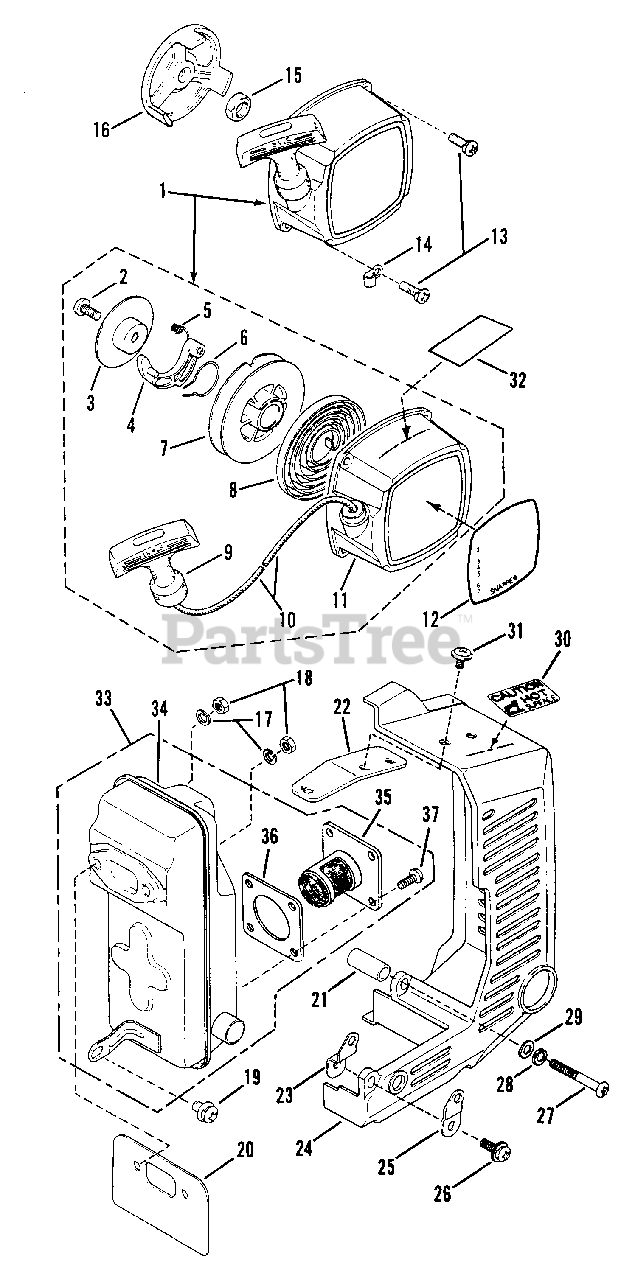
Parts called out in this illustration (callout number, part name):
1	RECOIL STARTER ASSM'Y.
3	PLATE, Friction
4	RATCHET
5	SPRING, Return
6	SPRING, Friction
7	REEL
8	SPRING, Spiral
9	KNOB, Starter
10	ROPE, Starter
11	CASE, Starter
12	DECAL, Instruction
16	PULLEY, Starter
17	LOCKWASHER
20	GASKET, Muffler
22	BRACKET
23	BRACKET
24	COVER, Muffler
25	BRACKET
28	LOCKWASHER
29	WASHER, Flat
30	DECAL, Caution
32	DECAL, Caution
33	MUFFLER ASSM'Y.
34	MUFFLER
35	SPARK ARRESTER
36	GASKET, Spark Arrester
37	SCREW, M4 x 8mm, PH
